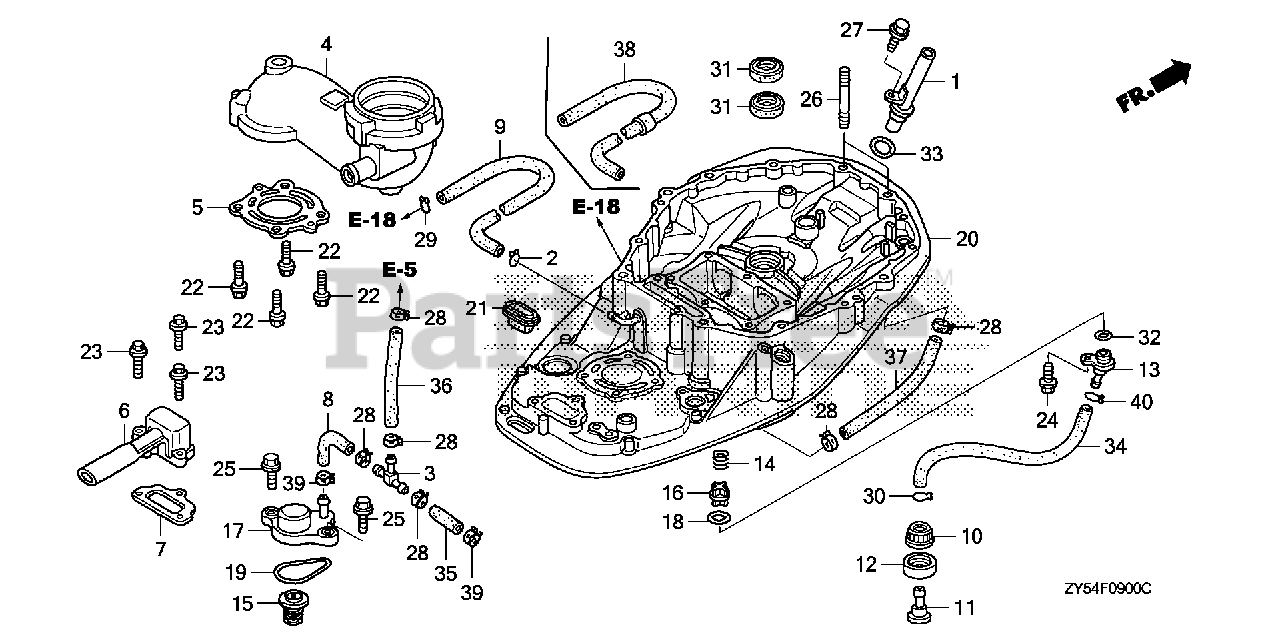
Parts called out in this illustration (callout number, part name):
1	PIPE, OIL LEVEL
2	CLIP, TUBE
4	GUIDE, EX. *NH8* (DARK GRAY)
5	GASKET, EX. GUIDE
6	PORT, IDLE EX.
7	GASKET, IDLE EX. PORT
8	TUBE, WATER RELIEF
10	NUT, WATER MOUTH
11	JOINT, WATER HOSE
12	SEAT, WATER MOUTH
13	COVER, FLUSH VALVE *NH8* (DARK GRAY)
13	COVER, FLUSH VALVE
14	SPRING, FLUSH VALVE
15	VALVE ASSY., RELIEF
16	VALVE, FLASH
17	COVER, RELIEF VALVE
18	GASKET, FLASH VALVE
19	O-RING, THERMOSTAT COVER
20	CASE, MOUNT *NH8* (DARK GRAY)
21	RUBBER, MOUNT CASE SEAL
22	BOLT, FLANGE (8X30)
23	BOLT, FLANGE (6X25)
24	BOLT, FLANGE (6X16) (ENGINE NO.)
24	BOLT, FLANGE (6X20) (ENGINE NO.)
25	BOLT, FLANGE (6X22)
26	BOLT, STUD (10X55)
27	BOLT, FLANGE (6X12)
28	CLAMP, TUBE (D10.5)
29	CLIP, TUBE (B12)
30	CLIP B1, TUBE
31	SEAL, WATER (22X35X7)
32	O-RING (16MM)
33	O-RING (11.5X3.5)
34	BULK HOSE, FUEL (8X1000) (8X300)
35	BULK HOSE, VACUUM (7X3000) (7X40)
36	BULK HOSE, VACUUM (7X3000) (7X160)
37	BULK HOSE, VACUUM (7X3000) (7X200)
38	TUBE F, WATER
39	CLAMP, TUBE (D10.5) (ENGINE NO.)
40	CLIP B1, TUBE
